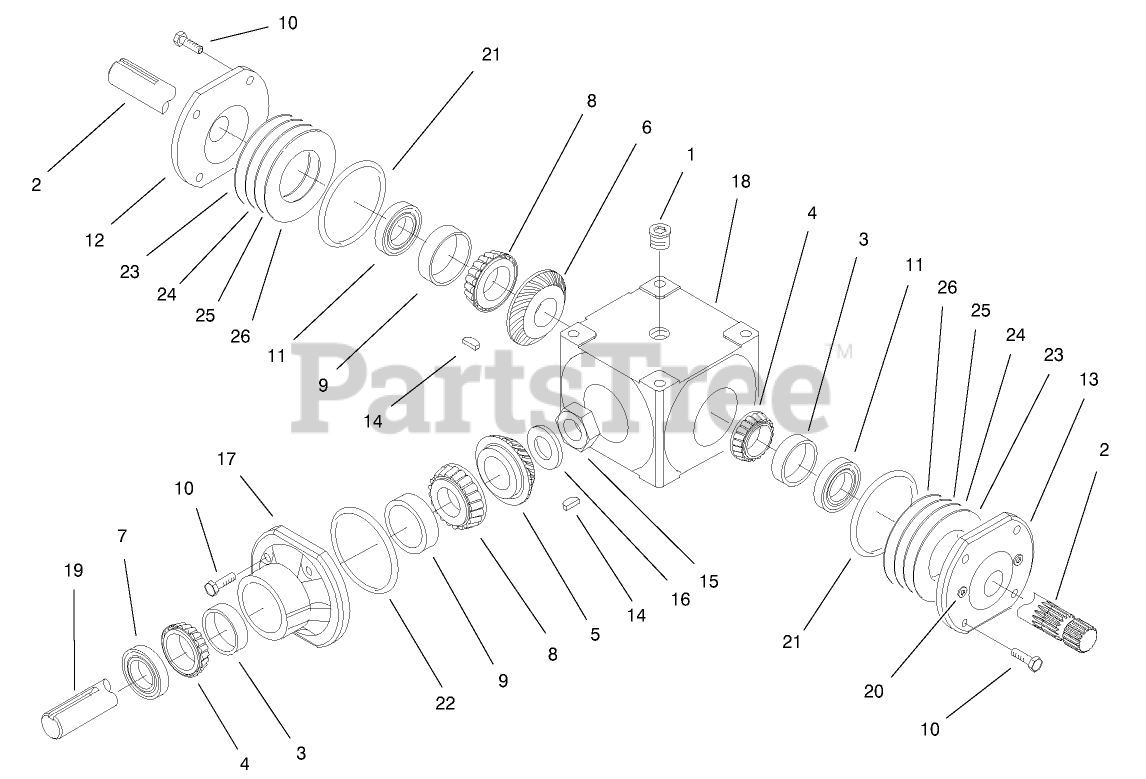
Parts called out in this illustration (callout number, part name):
2	Shaft-Cross
3	Bearing-Cup
4	Bearing-Cone
5	GEAR-SPIRAL, RH
6	GEAR-SPIRAL, LH
8	BEARING-CONE
9	BEARING-CUP
10	SCREW-HH
11	SEAL
12	CAP-END
13	END CAP W/ DRAIN PLUGS
14	OBS KEY
15	NUT-LOCK
16	WASHER
17	HOUSING-PINION
19	Shaft-Pinion
21	O-RING
22	O-RING
23	SHIM-GREEN (.003)
24	SHIM-BLUE (.005)
25	SHIM - BROWN (.010)
26	SHIM-YELLOW (.020IN)
